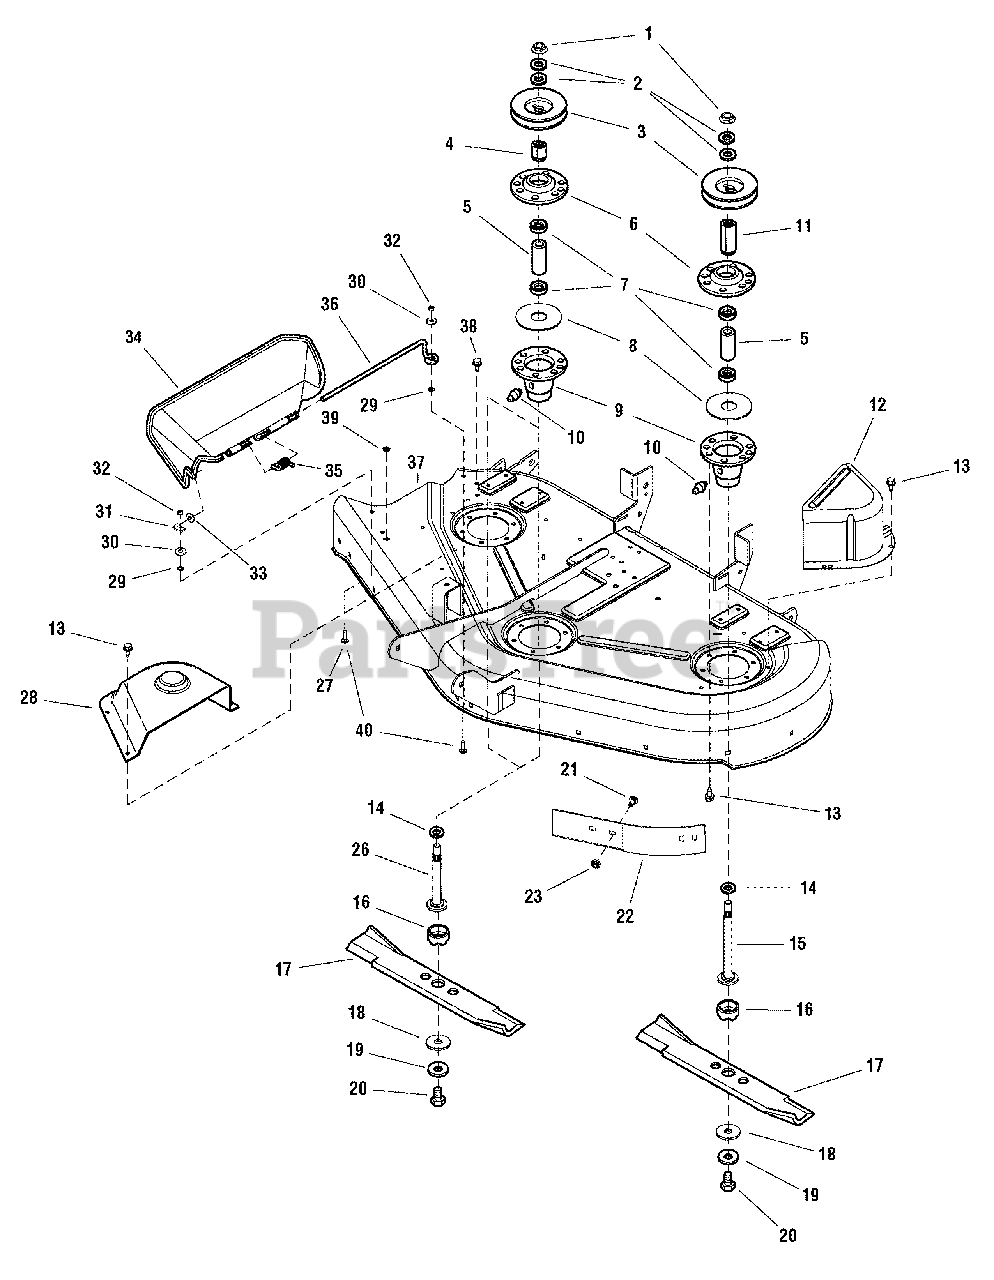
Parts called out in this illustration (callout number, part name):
1	NUT, Hex, Flange, 9/16-8
2	WASHER, Bellville .56ID x 1.34 OD x .05T
3	PULLEY, RH Arbor & LH Arbor, 4-1/4
4	HUB, Pulley, RH
6	COVER, Arbor Housing
8	GASKET, Foam
9	HOUSING ASSEMBLY, Arbor Bottom, w/Lube Fitting
10	FITTING, Grease
11	HUB, Adapter, LH
12	COVER, Arbor
13	CAPSCREW, Hex Head, Taptite, 5/16-18 x 3/4
15	SHAFT, Arbor
16	SHIELD, Grass, Lower
17	BLADE, Mower, 16-1/8
18	WASHER, Hex
19	WASHER, Spring
20	CAPSCREW, Hex Head, 7/16-14 x 1-1/4
21	BOLT, Carriage, 5/16-18 x 3/4
22	BAFFLE, Anti-Blowout
23	NUT, Hex, Flange Whizlock, 5/16-18
26	SHAFT, Arbor, RH
27	CARRIAGE BOLT, 1/4-20 x 1, Black
28	COVER, Arbor, RH
29	NUT, Push On
30	WASHER, Plain, 1/4 (6 Total for Export)
31	CLAMP, Wire, 5/16 Diameter
32	NUT, Hex Lock, ESNA, 1/4-20
33	WASHER, 5/16
34	DEFLECTOR, Plastic
35	SPRING
36	ROD, Deflector
37	HOUSING ASSEMBLY, 44" Mower Frame Mount (Red)
38	CAPSCREW, Taptite 3/8-16 x .75
40	BOLT
